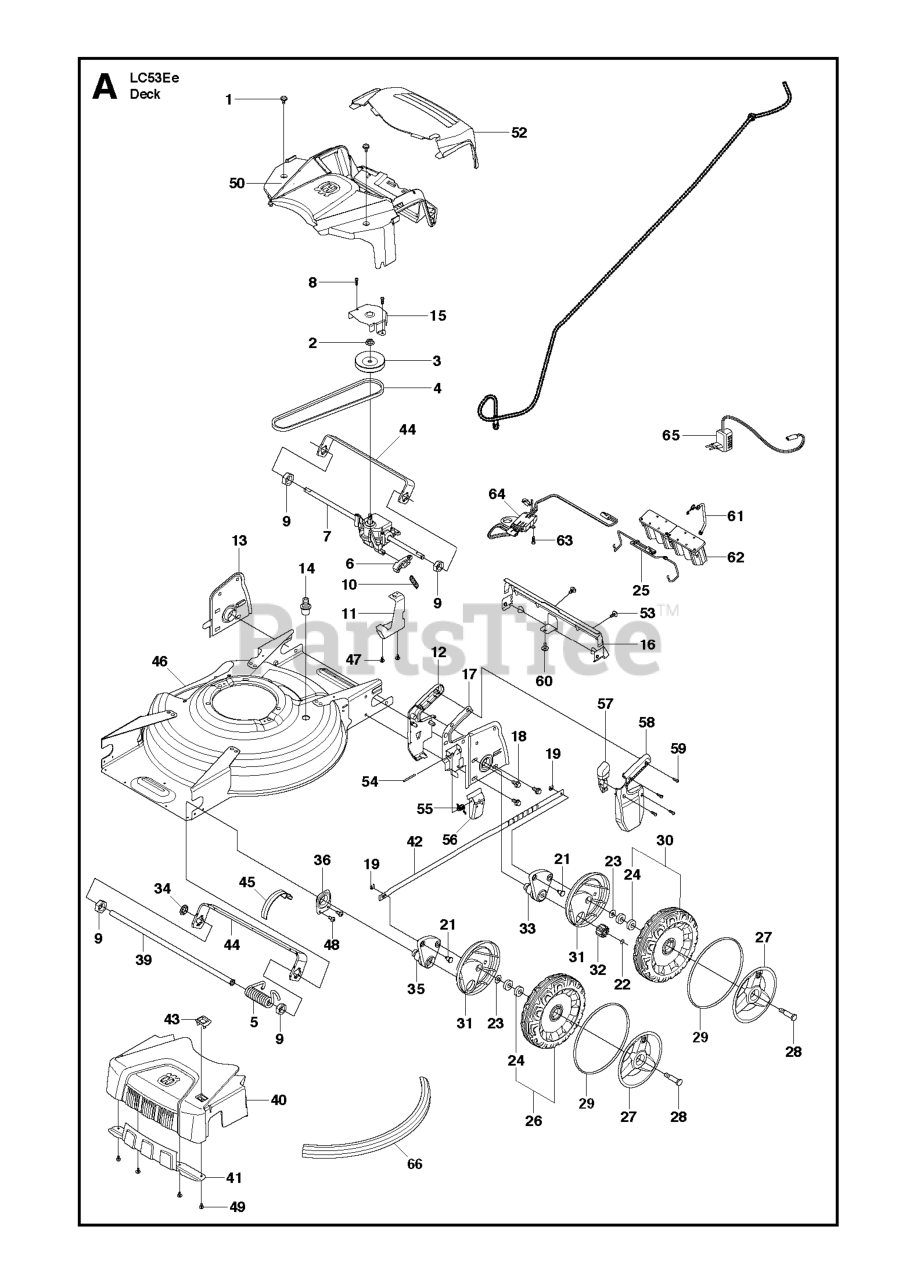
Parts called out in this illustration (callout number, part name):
1	SCREW ITXPANTT M5X10 ZPB (A00
5	SPRING
8	SCREW ITXPANT T50X16 ZN/FE (A
19	FASTENER
24	BALL BEARING
47	SCREW ITXPANTT M5X10 ZPB (A00
48	SCREW ITXPANTT M5X10 ZPB (A00
49	SCREW ITXPANTT M5X10 ZPB (A00
53	SCREW ITXPANTT M5X10 ZPB (A00
59	SCREW ITXPANT T50X16 ZN/FE (A
60	SCREW ITXPANTT M5X10 ZPB (A00
63	SCREW ITXPANT T50X16 ZN/FE (A
